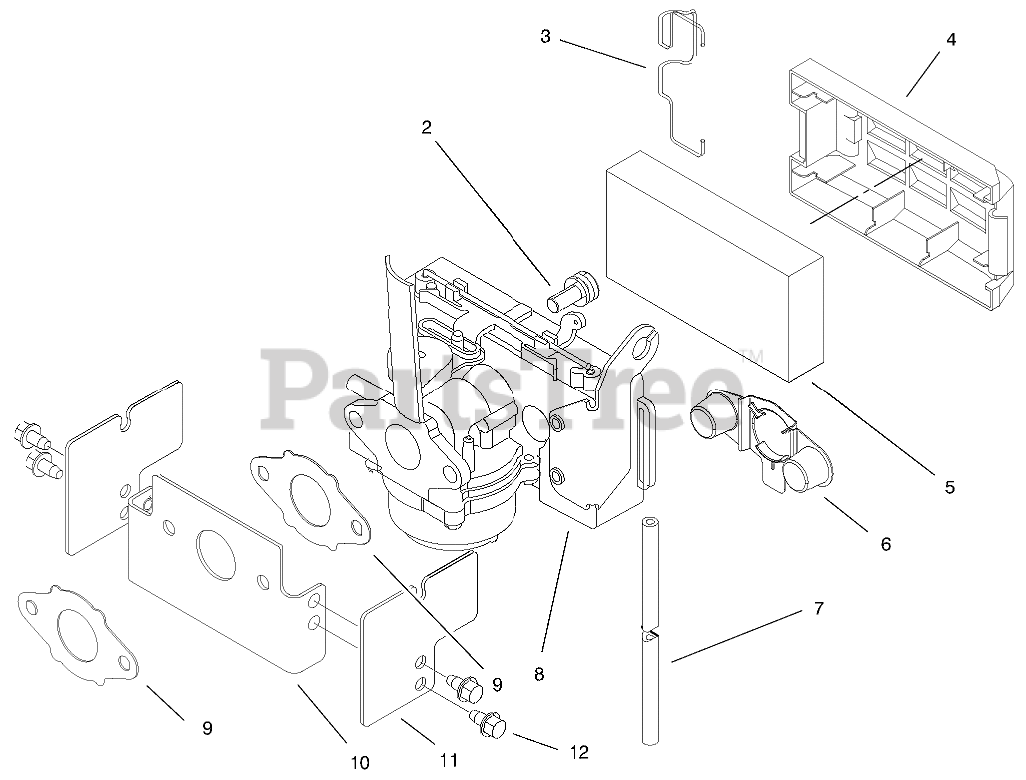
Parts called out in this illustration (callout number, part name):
2	SCREW
3	RETAINER-COVER, FILTER
4	COVER-AIR FIL. V
5	ELEMENT-AIR FIL VF
6	SHIELD-FUEL V
7	HOSE-PRIMER
8	Carburetor Assembly (Incl. Ref. #9)
9	GASKET CARB S
10	SHIELD-CARB V INTL
11	SHIELD- GOV. V INTL
12	SCREW V
